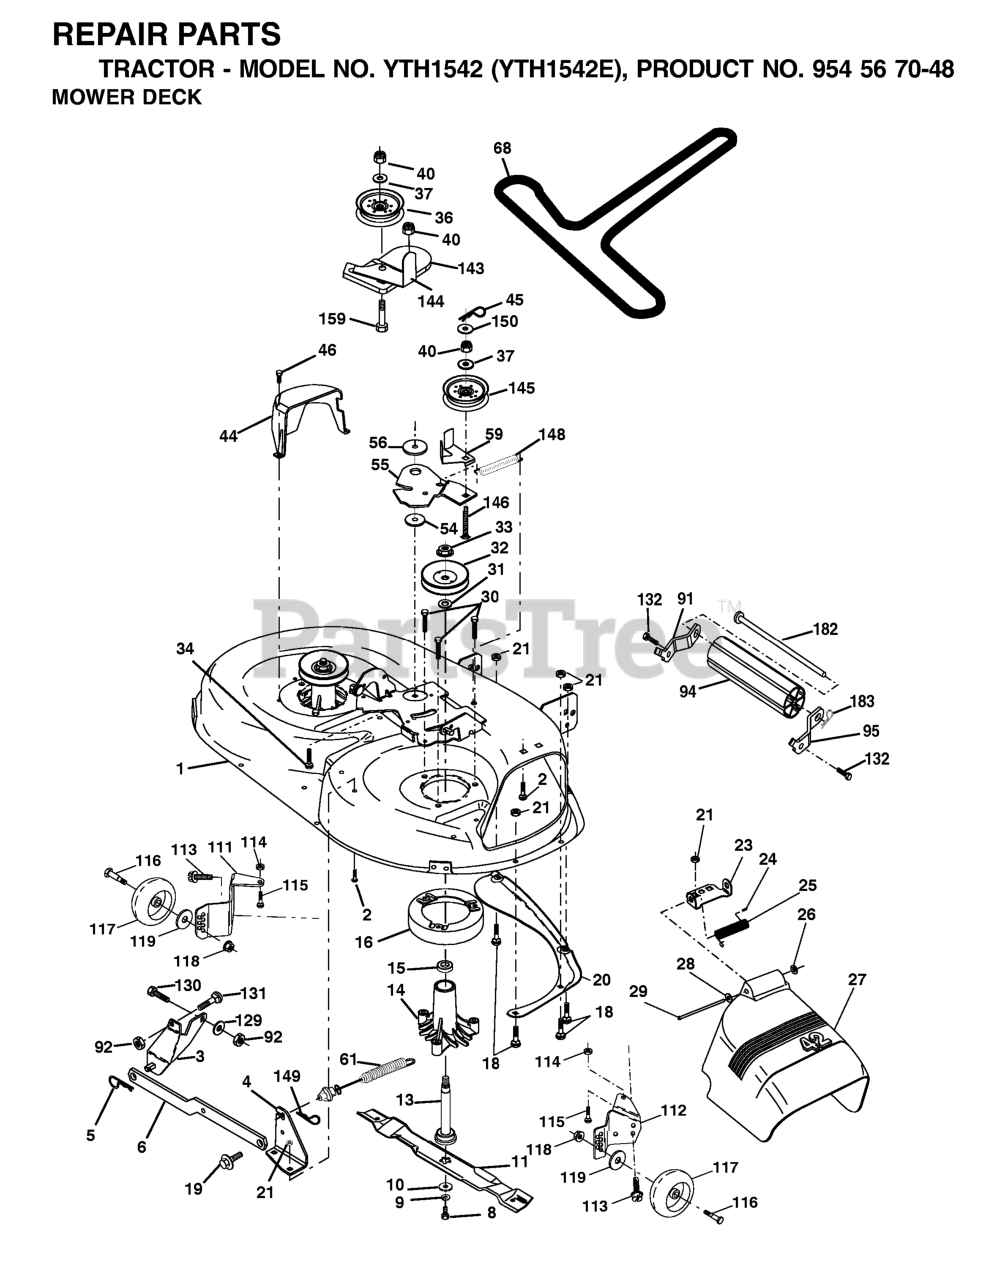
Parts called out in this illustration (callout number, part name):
1	42" DECK KIT
2	RP BOLT 5/16-18 X3/4 ZN/YEL GR
3	BRKT ASM SWAY BAR
4	BRACKET SWAY BAR 42" DECK
5	RETAINER-SPRNG RB
6	BAR SWAY DECK
8	BLADE BOLT
9	LOCKWASHER
10	WASHER.BLADE
11	Blade Mower 42" High Perf.
13	SHAFT ASM VENT
14	HOUSING.MANDREL.VENTED (MACHD)
16	STRIPPER.MANDREL.ROUND.BLACK
18	BOLT
19	BOLT SHD 5/16-18
20	BAFFLE.VORTEX
21	LOCKNUT
22	STIFFENER BRACKET
23	DEFLECTOR BRACKET
24	CAP-SLEEVE LT
25	SPRING TORSION
26	NUT PUSH M
27	SHIELD DEFLECTOR
28	Washer 11/32 x 5/8 x 16 Ga SD
29	ROD.HINGE
30	SCREW, WASHER HEAD
31	WASHER
32	PULLEY MANDREL
33	NUT, FLG TOPLOCK 9/16"
36	PULLEY.IDLER.FLAT
37	WASHER
44	GUARD MANDREL LH BLACK
45	RETAINER M
46	SCREW.1/4-20X5/8
54	HARDENED WASHER
55	ARM IDLER 42" MOWER LT/YT
56	SPACER RETAINER
59	GUARD TUV IDLER
61	SPRING EXT ELEC CLUTCH
68	V-BELT PRIMARY 42"
91	BRACKET ASM NOSEROLLER LH
94	NOSE ROLLER
95	BRACKET ASM NOSEROLLER RH
111	GUAGE WHEEL BRACKET LH
112	BRACKET WHEEL GUAGE KIT
113	Screw Tapping 3/8-16 x .625
114	NUT
115	BOLT.CARR.5/16-18X5/8.SHORT
116	BOLT, SHOULDER
117	WHEEL.GAUGE.STANDARD
118	LOCKNUT
119	WASHER.5/16.FLAT.STE.STD.
143	BRACKET, ARM IDLER
144	KEEPER BELT 42" CLUTCH
145	PULLEY.IDLER.FLAT.PLATED
146	BOLT, CARRIAGE IDLER BLACK
148	IDLER RETURN SPRING
149	SPRING.RETAINER.YELLOW.ZINC
182	ROD ROLLER NOSE STANDARD
183	SPRING RETAINER
